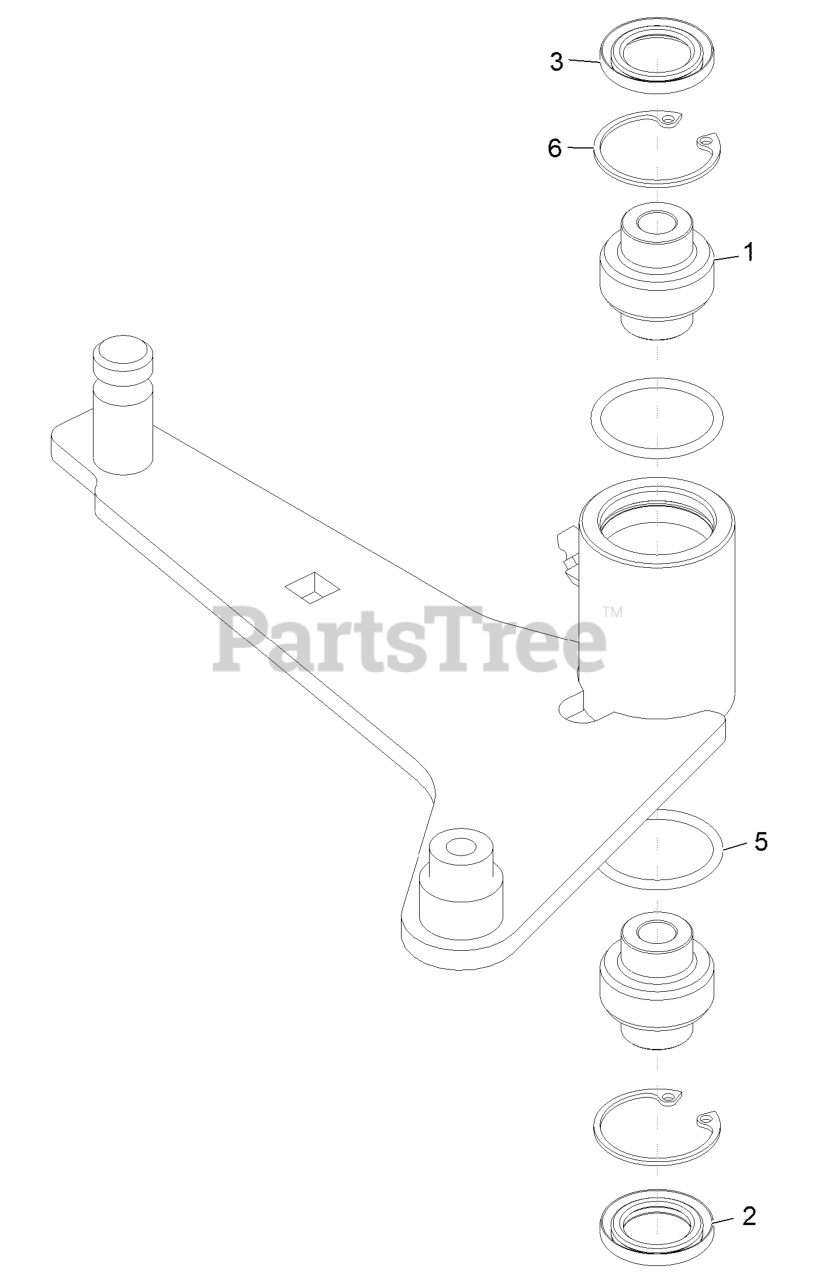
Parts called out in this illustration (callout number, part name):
1	Bearing-Spherical
2	Seal-Lip, Double
3	Seal-Single Lip
6	Ring-Retaining
